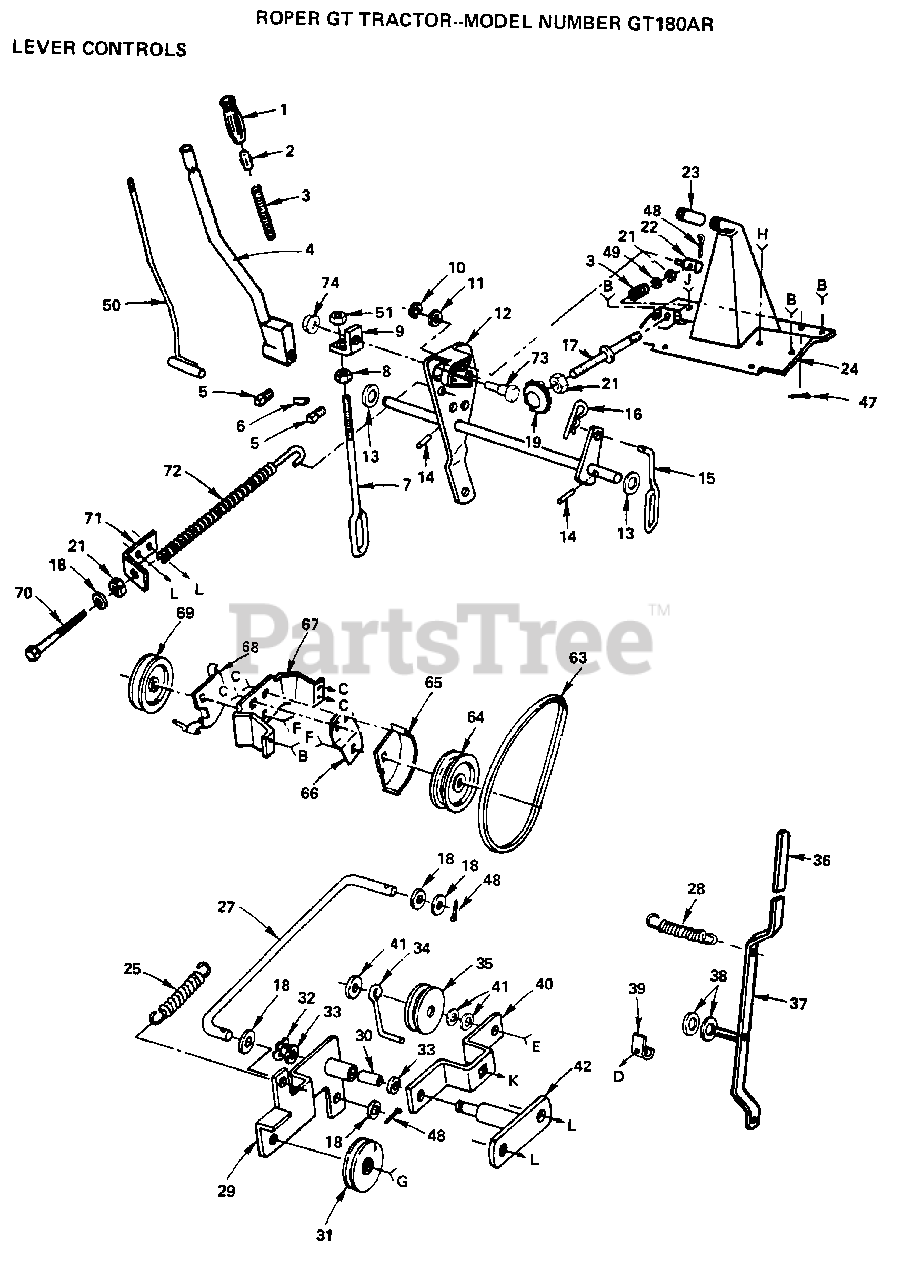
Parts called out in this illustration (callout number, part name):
1	HANDLE GRIP T
3	SPRING T
4	LEVER ASSY LT
7	LINK-LIFT MOW T
8	NUT.HEX.3/8-16UNC
9	BRACKET T
10	KLIP RING
11	WASHER
12	SHAFT ASSY GTV
13	WASHER
14	ROLL PIN STD
15	LINK - LIFT
17	ROD ADJUST LT
18	WASHER
21	NUT
23	"T, BEARING"
24	SUPPORT ASSY T
25	SPRING GTV
27	ROD CLUTCH GTV
30	"GTV, BEARING"
32	KLIP RING
33	WASHER T
38	WASHER
41	WASHER
42	BRACKET ASSY GTV
47	COTTER PIN
49	WASHER
50	ROD ASSY-LEVER LT
51	NUT
63	BELT-V.93.07
65	GUIDE-BELT T
67	BRACKET - V IDLER
69	PULLEY V IDLR GTV
70	BOLT-ADJ SPRING T
73	SHOULDER BOLT T
74	NUT T
